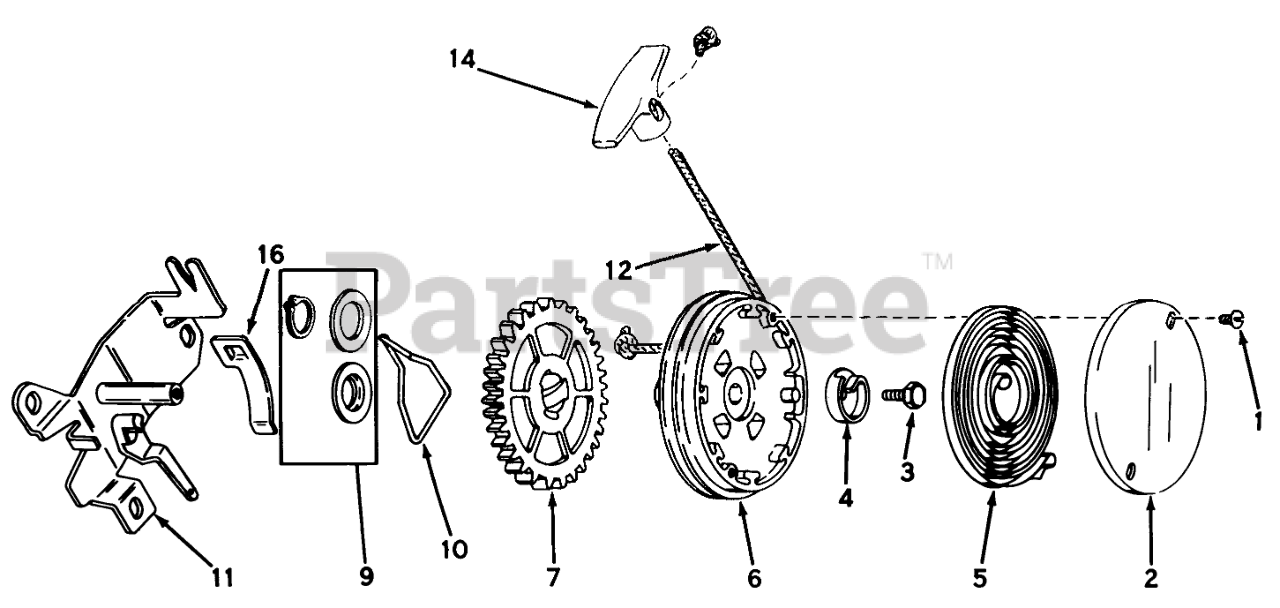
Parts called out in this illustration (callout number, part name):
2	Cover, Spring
3	Screw, Hex Washer Head
4	Hub Spring
5	Spring, Rewind
6	Pulley Assy. (Incl. #9)
9	Kit, Thrust Wash. & Snap Rg.
11	Bracket Assy., Mounting
12	Rope-Starter
14	Handle-Starter
16	Clip Rope
